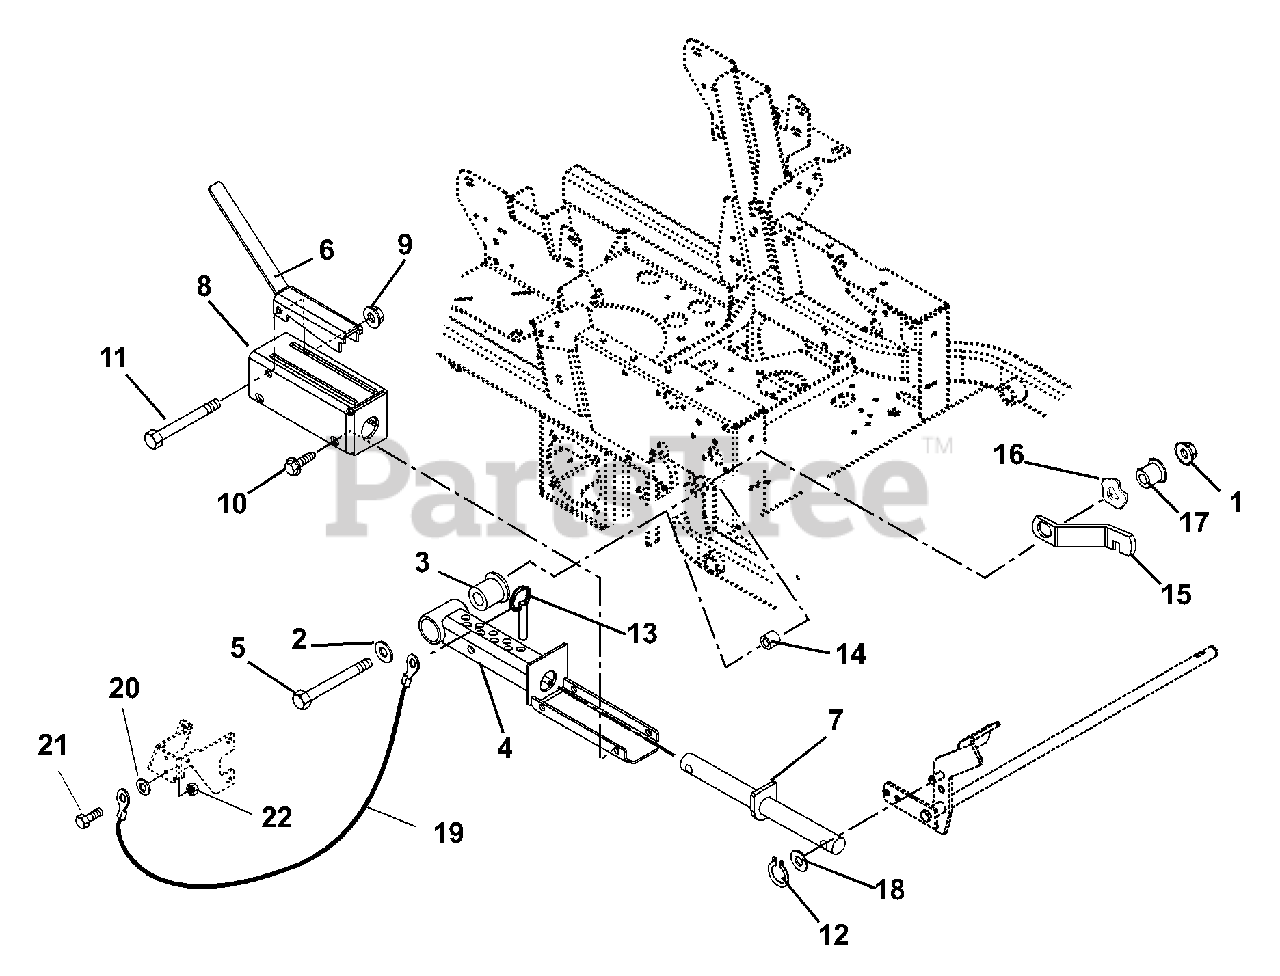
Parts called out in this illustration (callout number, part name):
1	Nut, Locking Top Flange .50-13
2	Washer, Flat Steel .531 x 1.25 x .10
3	Bearing, Pedestal
4	Weldment, Mechanical Lift
5	Bolt-Hex .50-13 x 5.00 Grade 5
6	Lock-Up, Mechanical Lift
7	Weldment, Mechanical Lift Shaft
8	Weldment, Mechanical Lift Cover
9	Nut, Locking Top Flange .38-16
10	Screw, Tapping .38-16 x .50 Hex Washer Head
11	Bolt, Hex .38-16 x 3.25 Grade 5
12	Ring, Retaining External .625 x .05
13	Pin, Spring Ball .375 O.D. x 1.50
14	Spacer .516 ID x 1.00 OD x .875
16	Washer-Wave .076 x 1.120 x .080
17	Bushing-Flange .515 x .750 x .275 x 1.120
18	Washer, Flat Steel .656 x 1.31 x .095
19	Cable, Hood
20	Washer, Flat Steel .265 x .50 x .087
21	Bolt-Hex .25-20 x .75 Grade 5
22	Nut, Locking Top Flange .25-20
